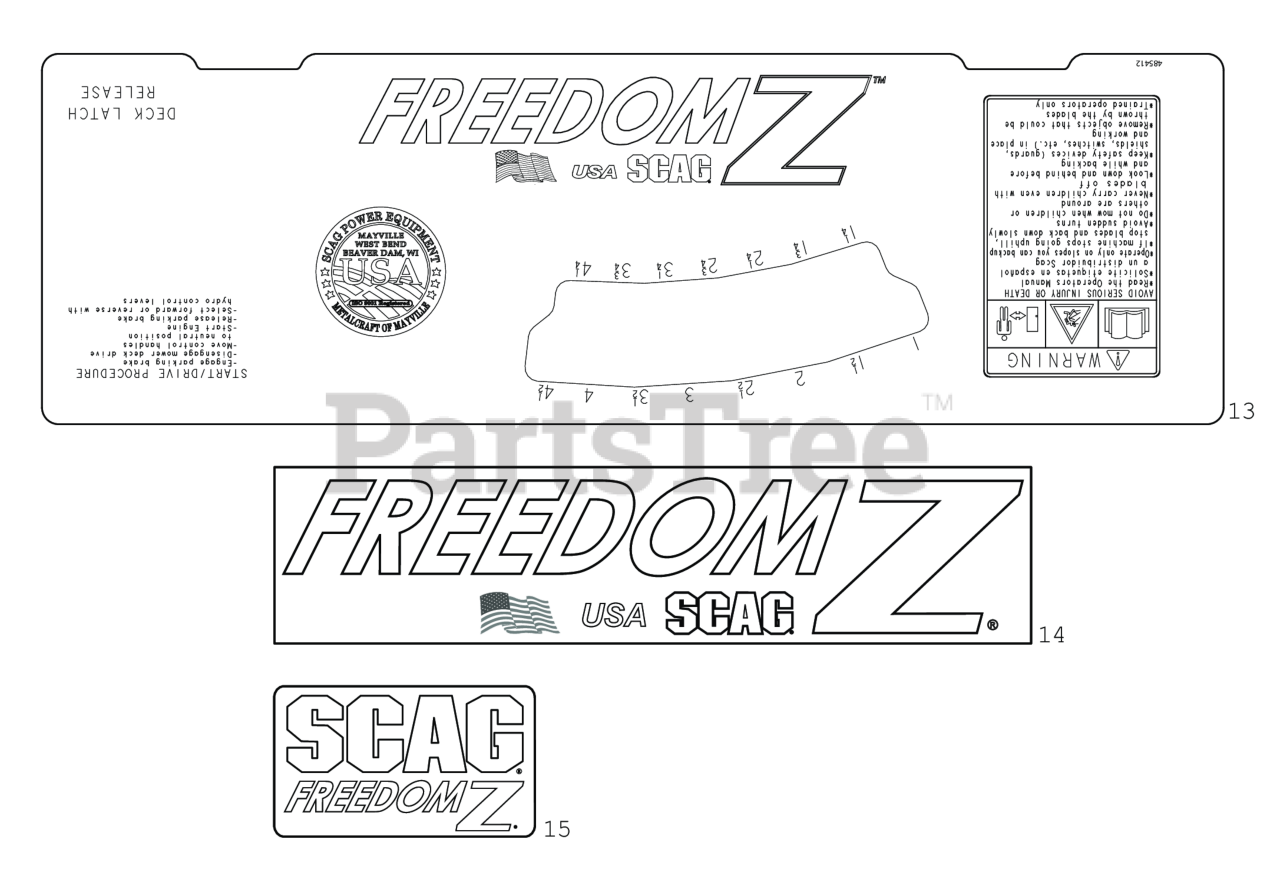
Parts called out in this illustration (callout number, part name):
13	Decal, Cutting Height
14	Decal, Freedom Z (Fuel Tank)
15	Decal, Scag Freedom Z (Fuel Tank)
